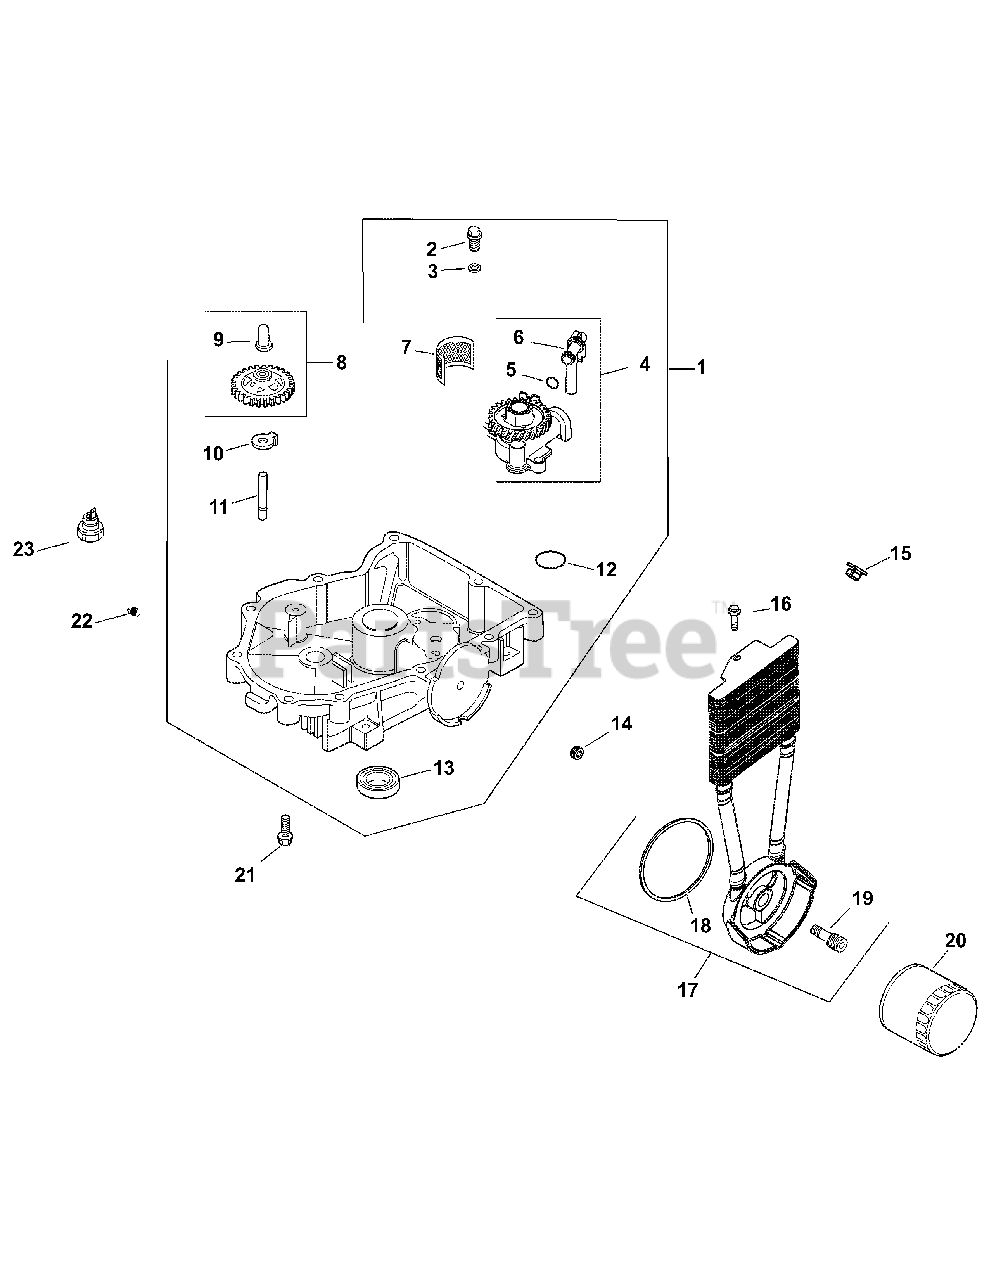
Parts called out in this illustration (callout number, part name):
1	Pan, Oil Assembly
2	Screw, Flg Thd Frm M6X1.0X25
3	Washer, Flat 6MM
4	Kit, Oil Pump Assembly
5	O-Ring, Oil Pick-Up
6	Tube, Oil Pick-Up
8	Kit, Governor Gear w/ Pin
9	Pin, Governor Regulating
11	Shaft, Governor Gear
14	Plug, Pipe CTSK 3/8"
15	Nut, Plastic
16	Screw, Tap M6x1.7x18
17	Kit, Oil Cooler (Metal)
18	O-Ring, Oil Cooler
19	Nipple, Oil Filter
21	Screw, Flg M8x1.25x45
22	Plug, Hd Pipe 3/8"
23	Switch, Oil Pressure
